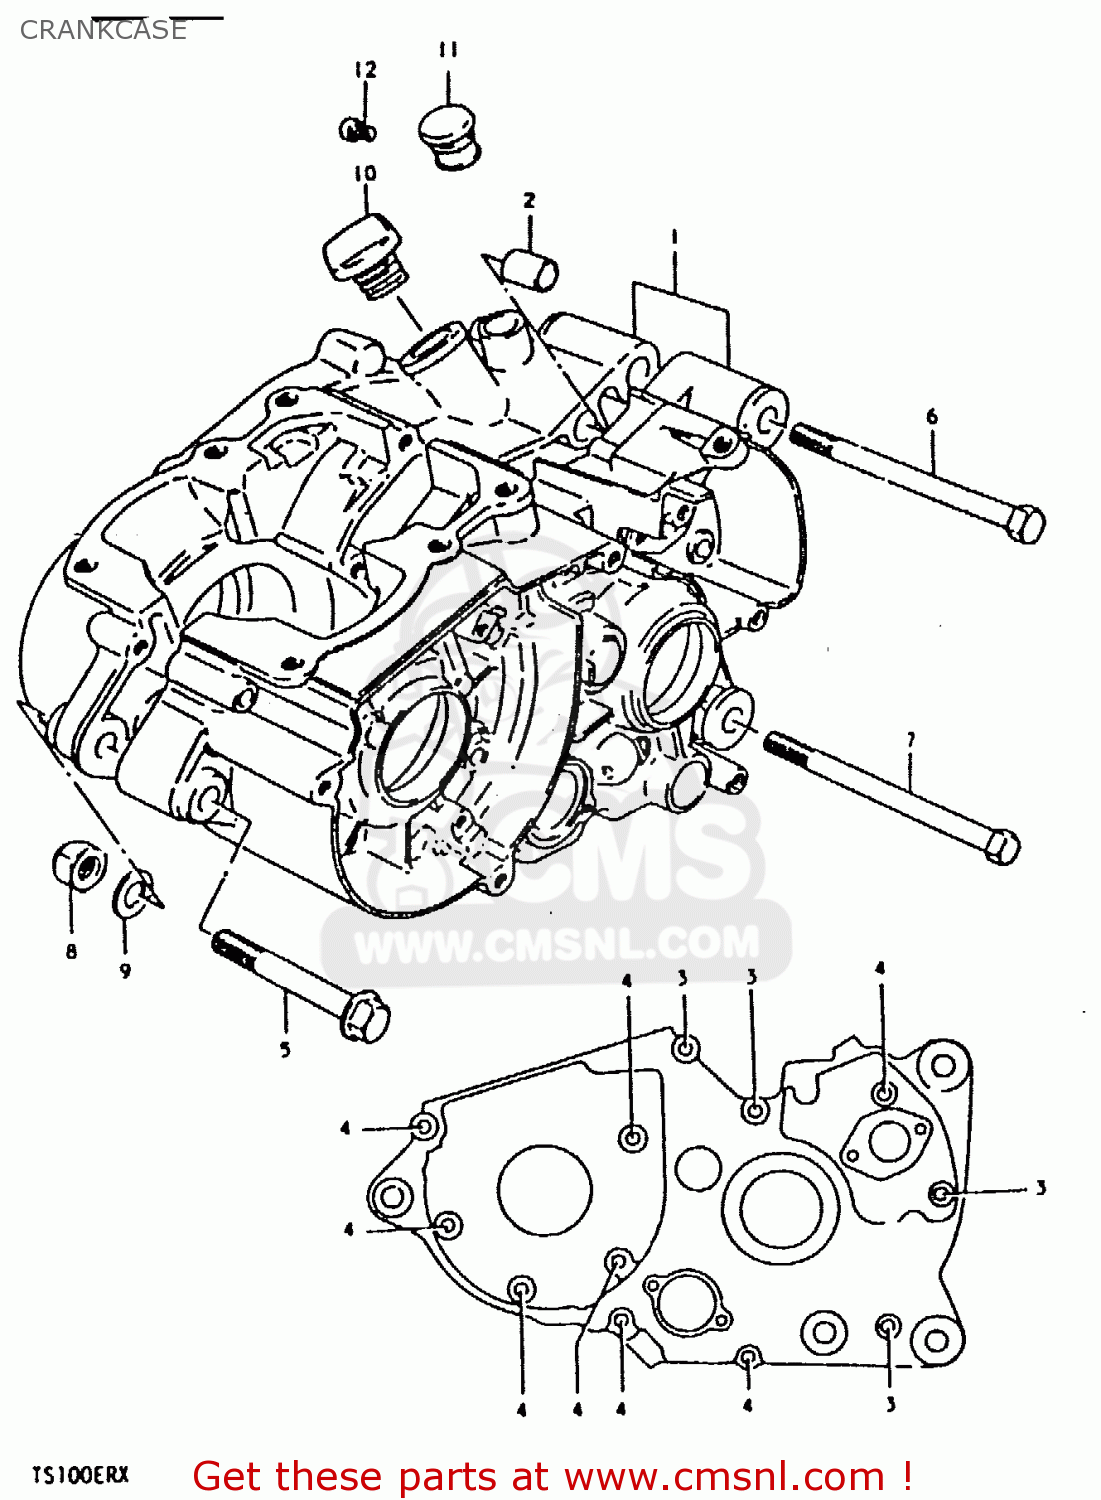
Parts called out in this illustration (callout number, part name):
1	CRANKCASE ASSEMBLY
2	PIN
3	SCREW
4	SCREW 6X60
5	BOLT (10X75)
6	BOLT(10X110)
7	BOLT
8	NUT
9	WASHER
10	PLUG
11	Plug
12	SCREW,6X6
